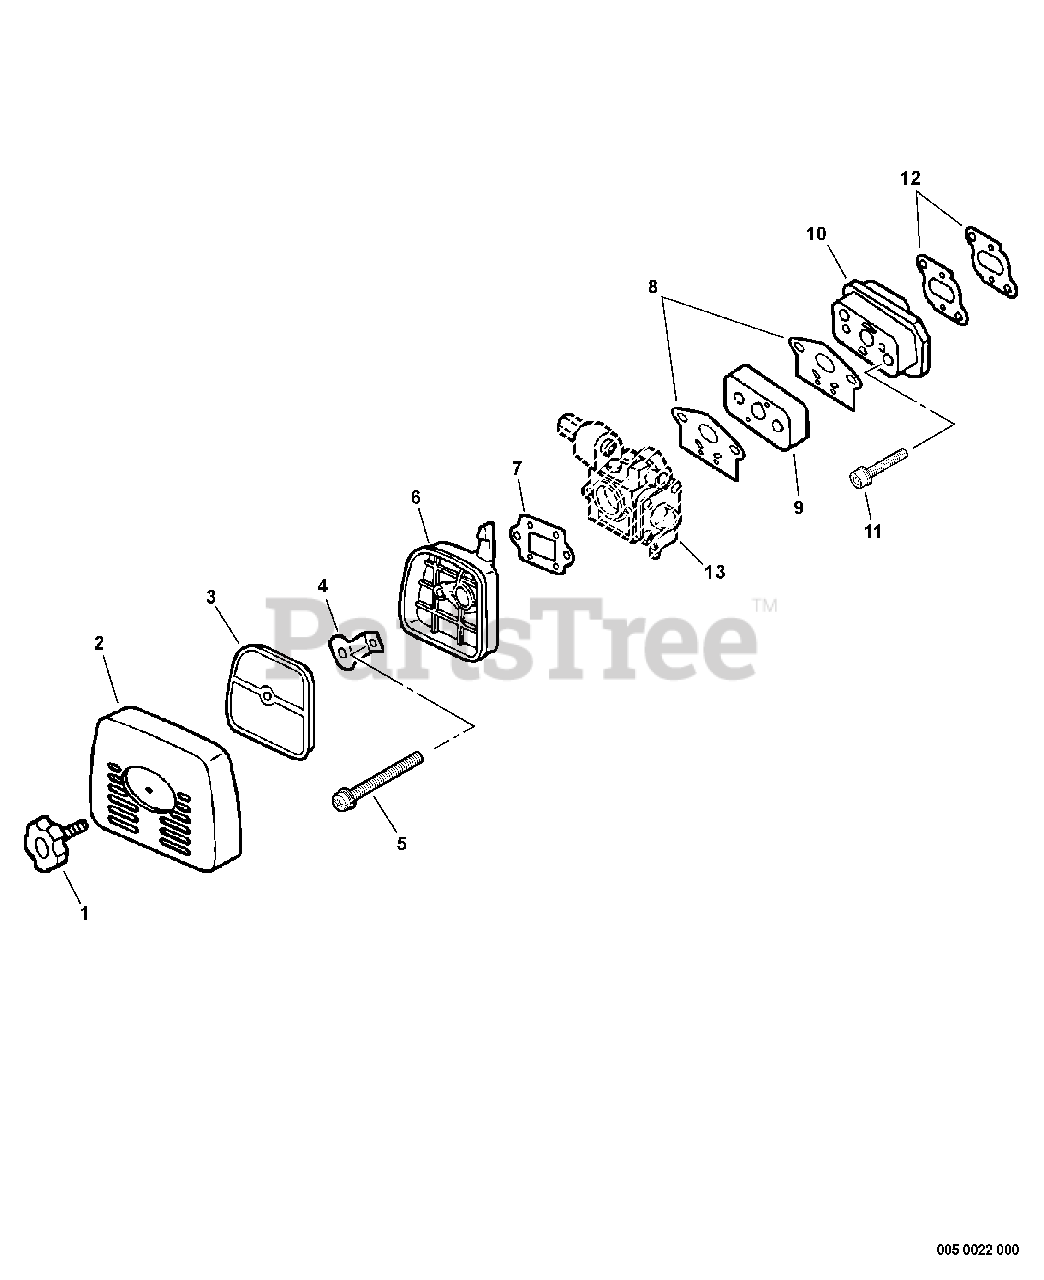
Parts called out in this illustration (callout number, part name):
1	THUMBSCREW
2	COVER, AIR FILTER
3	FILTER, HEAVY-DUTY AIR
4	PLATE, PREVENT
5	SCREW 5×65
6	CASE, AIR FILTER
8	GASKET, CARBURETOR
9	INSULATOR, INTAKE
10	INSULATOR, INTAKE
11	BOLT 5×25
12	GASKET, INTAKE
13	CARBURETOR
